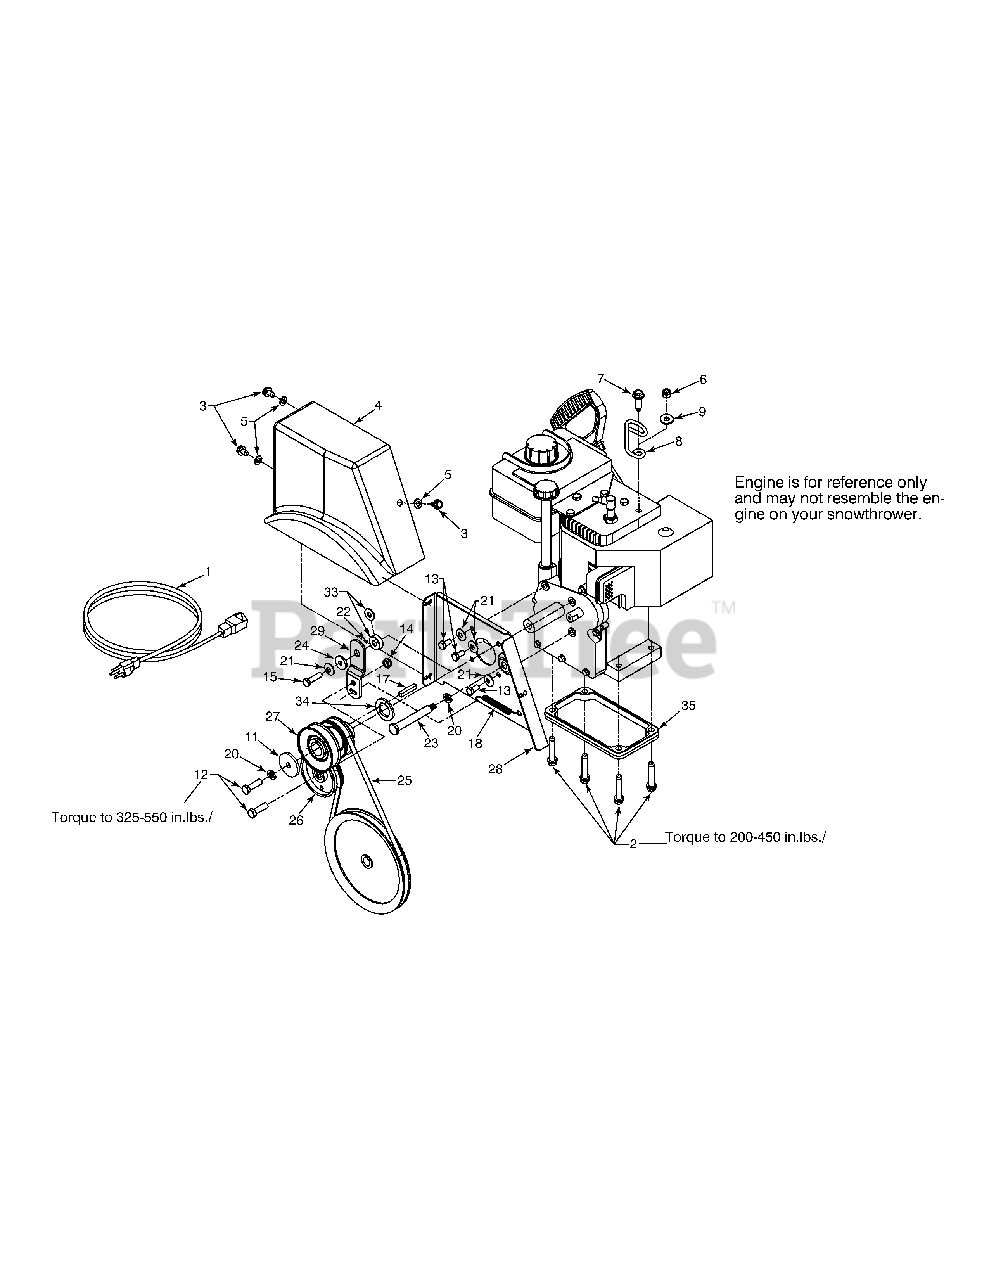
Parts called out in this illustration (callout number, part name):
1	Extension Cord 10 Ft.
2	Hex L-Wash TT Scr. 3/8-16 x 1.8 (for 10 & 11 HP)
2	Hex Washer Scr 3/8-16 x 1.25 (for 12 & 13 HP)
3	Hex Wash HD S-Tapp Scr 5/16-18 x .50
4	Plastic Belt Cover
5	Flat Washer .330 ID x .630 OD x .0635
6	Hex Flg. L-Nut 1/4-20 Gr. F Nylon
7	Hex Wash Hd Tapp Scr 5/16-18 x 1.00
8	Cable Control Wire
9	Flat Washer .28 ID x .74 OD x .063
11	Flat Washer .450 ID x 1.250 OD x .164
12	Hex Screw 3/8-24 x 1.25 Gr. 8 Special
13	Hex Screw 5/16-24 x .625 Gr. 5
14	Hex Nut 3/8-24 Gr. 5 Nylon
15	Hex HD. Cap Scr. 5/16-24 x 1.25 Lg. Gr 5 (for 10 & 11 HP)
15	Hex Screw 5/16-24 x .875 Gr. 5 Lock (for 12 & 13 HP)
17	Square Key 1/4 x 1/4 x 1.50" Lg.
18	Brake Return Ext. Spring 3.18" Lg.
20	Lockwasher Heavy 3/8" ID
21	Cupped Washer .340 ID x .872 OD x .06
22	Grease Arctic
23	Shoulder Screw .498 x 3.245 x 3/8-16 (for 10 & 11 HP)
23	Shoulder Screw .498 Dia x 3.00 (for 12 & 13 HP)
24	Shoulder Spacer .25 THK
25	V-Belt 3/8 x 35.5" Lg.
26	Flat Idler w/flanges 3.0 OD
27	Double Groove Engine Pulley
33	Spacer .33 ID x 1.01 OD x .36 (for 10 & 11 HP)
33	Flat Washer .349 ID x .879 OD x .063 (for 12 & 13 HP)
34	Spacer 1.02 x 1.63 x .1425 (for 10 & 11 HP)
35	Engine Spacer .560 Thick (for 10 & 11 HP)
